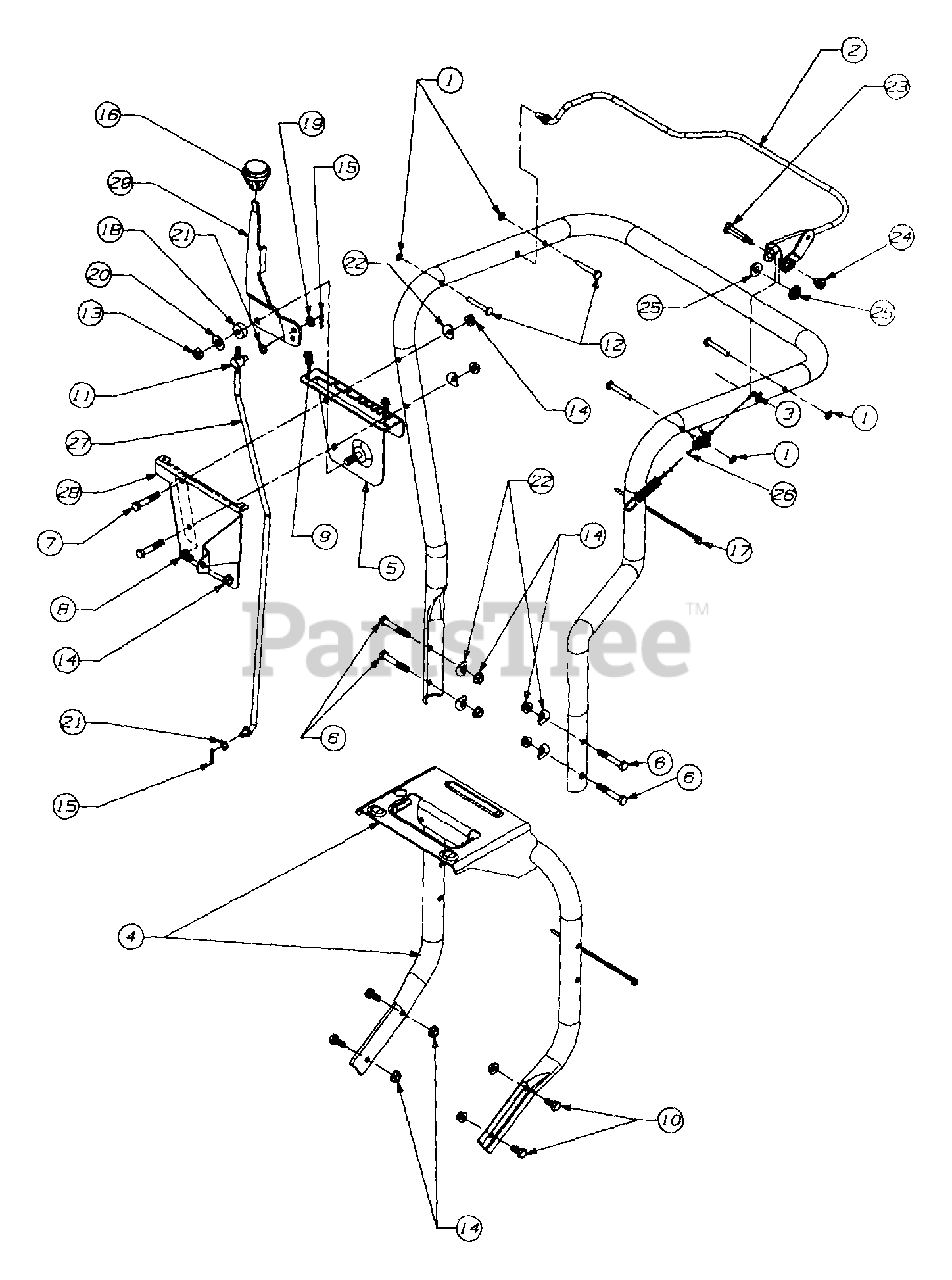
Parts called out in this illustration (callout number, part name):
7	SCREW - HEX
8	SCREW - HEX
11	FERRULE
12	PIN - STUD
13	NUT - HEX LOCK
14	NUT - HEX LOCK
15	PIN - COTTER
16	KNOB - SHIFT
18	WASHER - RUBBER
19	WASHER - FLAT
20	WASHER - FLAT
21	WASHER - SPRING
22	WASHER - SADDLE
23	SCREW - SHOULDER
24	NUT - SHOULDER
25	BEARING - FLANGE PLASTIC
26	CABLE - CLUTCH
